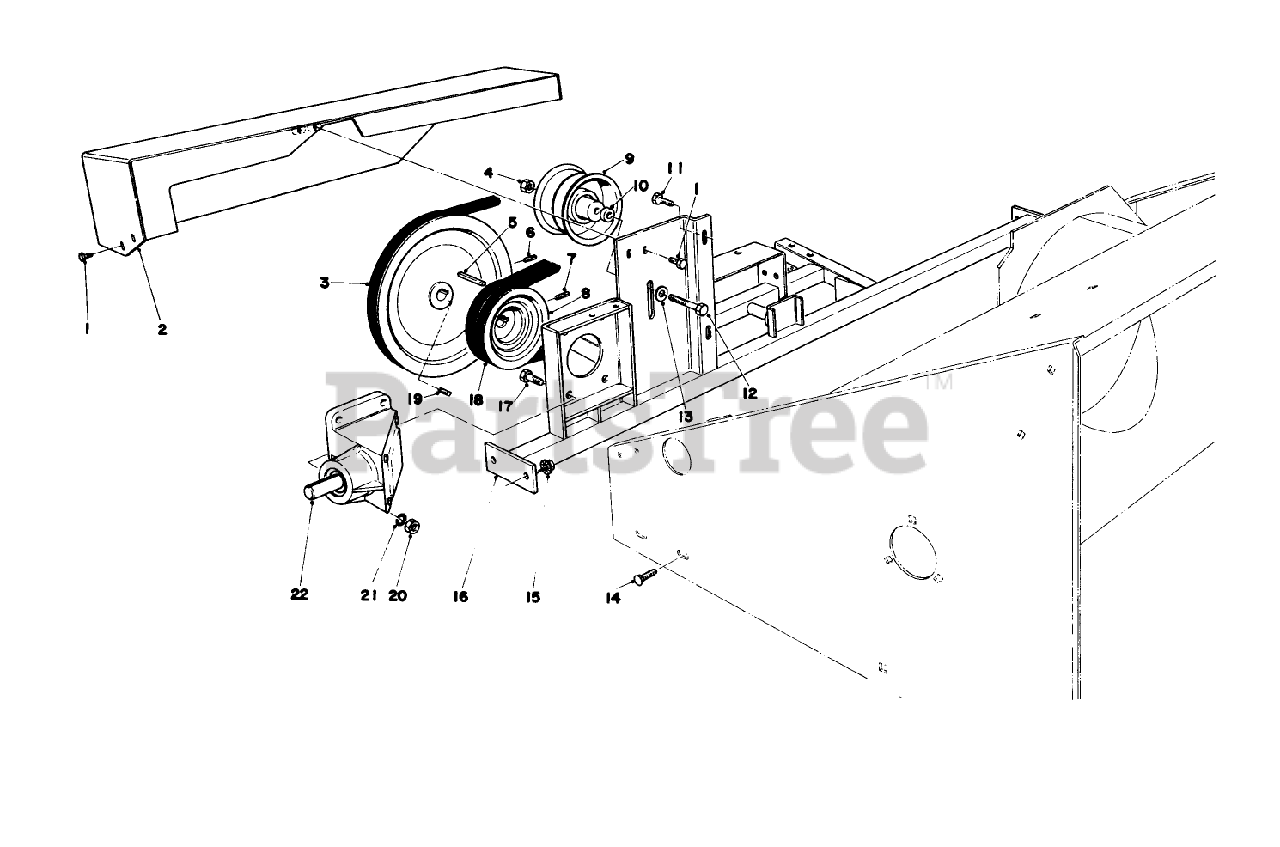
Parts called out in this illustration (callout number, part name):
1	SCREW-HHF
2	BELT SHIELD WA
3	SHEAVE 60014
4	NUT-LOCK, CONE
6	SCREW-SQH
7	SCREW-SET, SQH
8	PULLEY
9	Idler Pulley
10	IDLER SPACER
11	SCREW-HH
12	SCREW-HH
13	WASHER-FLAT
14	SCREW-CARR
15	NUT-HHF, WHIZ
16	Cross Brace
17	SCREW-HH
18	V-BELT
19	SCREW-SET, SQH
20	NUT-HEX
21	WASHER-LOCK
22	Gear Box Assembly
